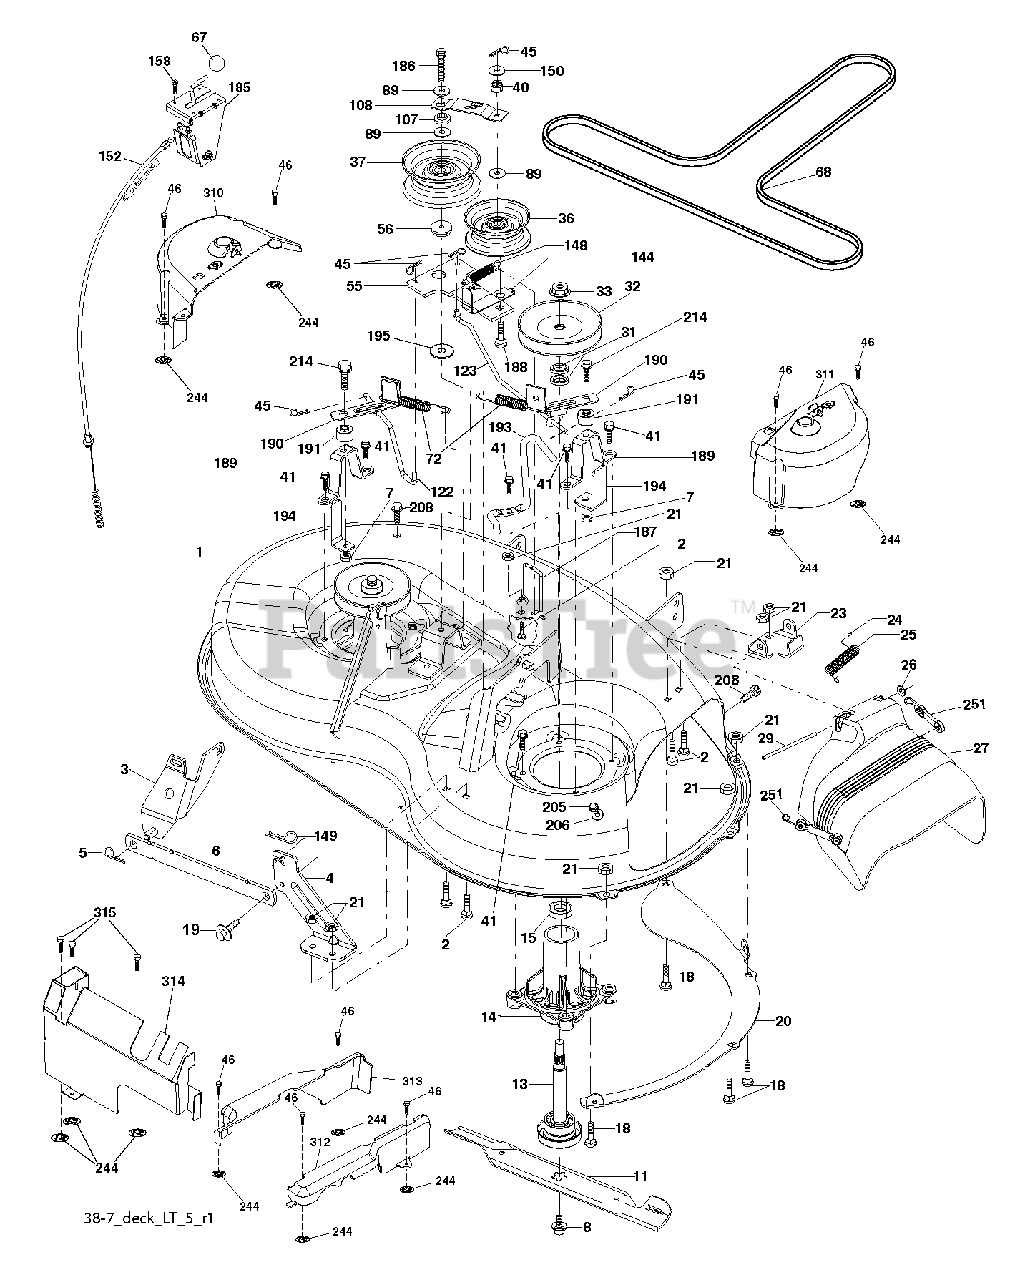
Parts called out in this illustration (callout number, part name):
1	DECK SVC 38/94 192556X431
2	BOLT 5/16-18 X3/4 ZN/YEL GR 5
3	BRKT ASM SWAY BAR
4	BRACKET DECK SWAY BAR 38"/42"
5	Retainer Spring
6	BAR SWAY DECK
7	NUT.71038.31-18.HEX.NYLOCK
8	BOLT.WASHER.ASM.7/16-2
11	BLADE 38" PREMIUM
13	SHAFT.ASM.MDRL.N/GREASE.38
14	HOUSING.MANDREL.4PT.
18	BOLT
19	BOLT SHD 5/16-18
20	BAFFLE.VORTEX.FRONT.38"
21	LOCKNUT
23	BRKT.DEFLECTOR.38"2005+
24	CAP-SLEEVE LT
25	SPRING.TORSION.DEFLECT
26	NUT PUSH M
27	SHIELD ASM.DFLCTR MWR.38-7"BLK
29	ROD.HINGE
31	WASHER.SPACER.MANDREL
32	PULLEY MANDREL
33	NUT.FLANGE.LOCK.TOP
36	FLAT IDLER PULLEY
37	PULLEY.IDLER.FLAT.UNPLATED
41	BOLT.HEX.WASHR.HED.313-18X1.19
45	RETAINER M
46	SCREW.1/4-20X5/8
56	SPACER.RETAINER.MOWER
67	KNOB T (3/8 HOLE)
68	V-BELT.MOWER.38"2005+
72	SPRING.BRAKE.RETURN.38"
89	WASHER
107	SPACER.IDLER.ARM
108	STIFFENER.IDLER.ARM
122	LINK.BRAKE.38"LEFT.2007
123	LINK.BRAKE.38"RIGHT
144	KEEPER BELT
148	IDLER RETURN SPRING
149	SPRING.RETAINER.YELLOW.ZINC
152	CABLE.CLUTCH.38".SERVICE
158	SCREW
185	HEAD ASM. CABLE CLUTCH
186	SCREW.HXWSH.3/8
187	KEEPER BELT
188	BOLT, CARRIAGE IDLER
189	STAND, BRAKE
190	ARM, BRAKE
191	BRAKE.SPACER.38".DECK
193	KEEPER BELT RH MANDREL
194	GUARD BRAKE
195	WASHER 12/32X2X10GA
205	SCREW
208	SCREW 3/8-16X1/2
214	BOLT/WASHER ASM 5/16-18
244	PALNUT 1/4
251	ELASTIC STRAP KIT
315	SCREW 1/4X20
